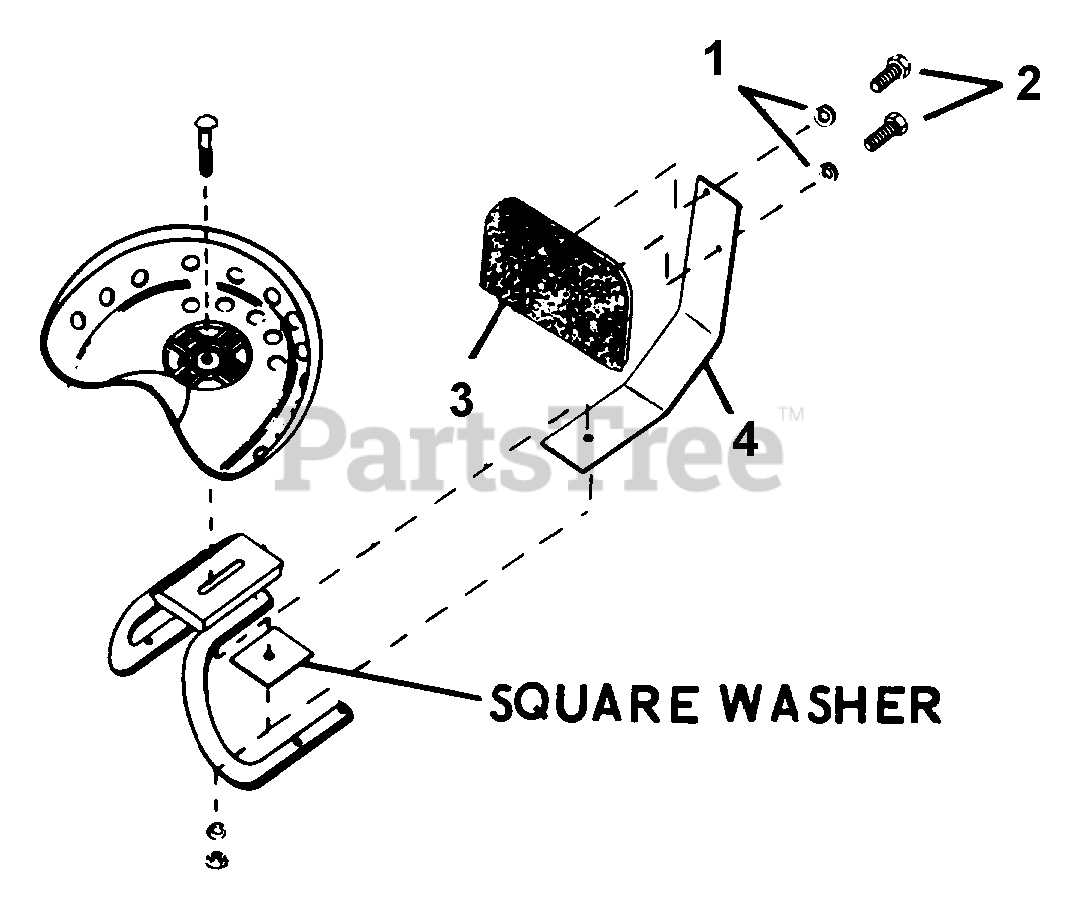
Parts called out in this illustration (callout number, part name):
1	WSHR-LK .312X.097 PL HVY
2	BLT-HEX .31-18X.75 PL GR2
3	BACK REST
4	SEAT BACK SUPPORT
